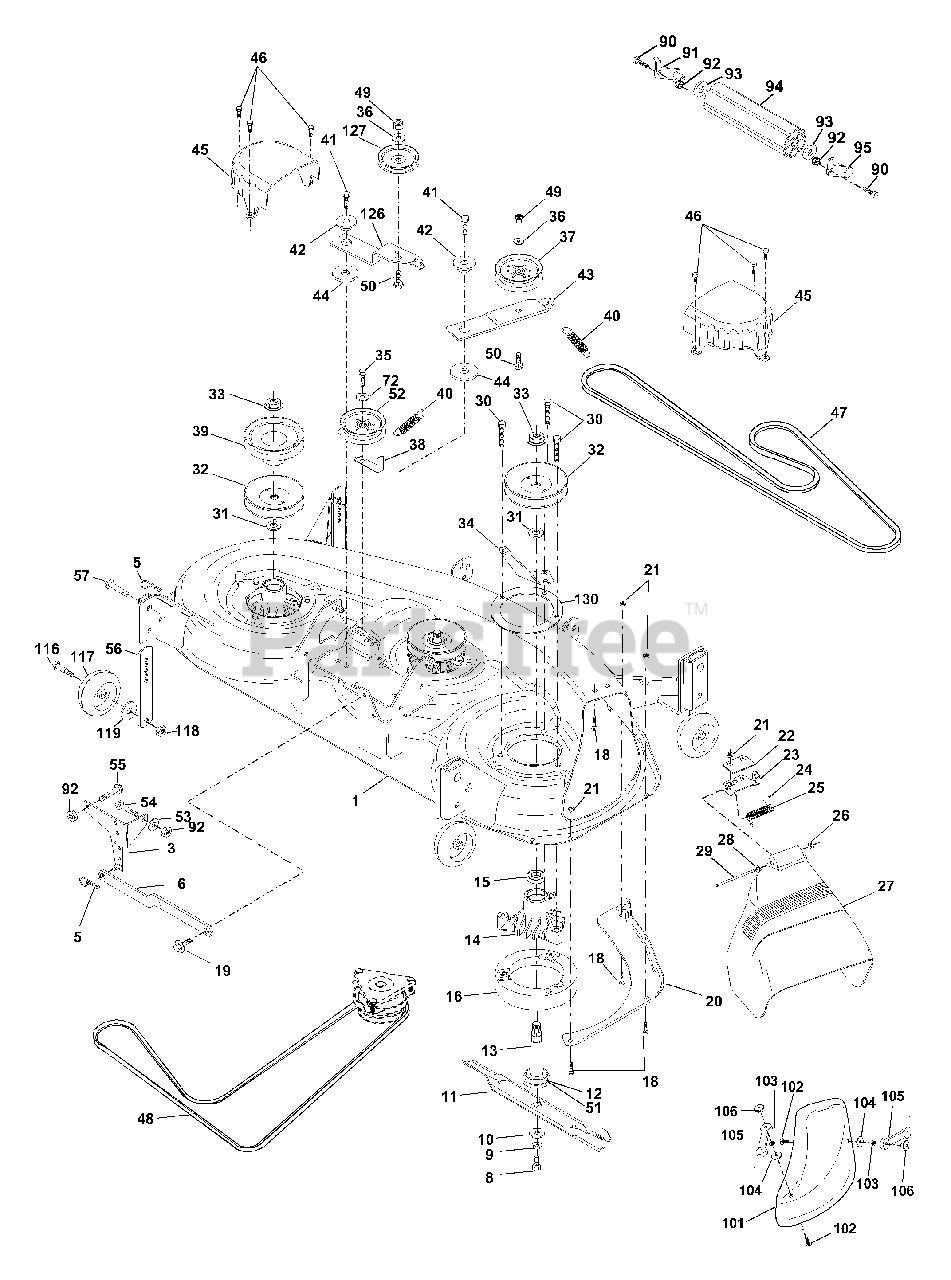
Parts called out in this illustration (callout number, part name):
1	Deck Asm., Mower 46"
3	Bracket Asm., Sway Bar
5	Retainer Spring
6	Arm, Suspension, Rear (Sway Bar)
8	Bolt, Patched 3/8-24 x 1-1/4 Gr. 8
9	Washer, Lock Hvy., Unplated 3/8
10	Washer, Hard Blade, Mower Vented
11	Blade, 46" Hi Perf
11	Blade, 46" Mulching
12	Bearing, Ball, Mandrel #6204
13	Shaft Asm. w/Lower Bearing
14	Housing, Mandrel
15	Bearing, Ball, Mandrel
16	Stripper, Mower Round
18	Bolt, Carriage 5/16-18 x 5/8
19	Bolt, Hex Head, Shoulder 5/16-18
20	Baffle, Vortex Mower 46"
21	Nut, Crownlock 5/16-18 UNC
22	Stiffener, Bracket
23	Bracket, Deflector
24	Cap, Sleeve
25	Spring, Torsion, Deflector
26	Nut, Push
27	Shield, Deflector Mower
28	Washer 11/32 x 5/8 x 16 Ga.
29	Rod, Hinge
30	Screw, Wsh Head, Thdroll
31	Washer, Spacer Mower Vented
32	Pulley, Mandrel
33	Nut, Flg. Top Lock Cntr. 9/16
34	Anchor, Spring Deck 46"
35	Screw, Thdroll 3/8-16 x 1-3/4 Tytt
36	Washer 13/32 x 13/16 x 16 Ga.
37	Pulley, Idler, Flat
38	Keeper, Belt, Idler
39	Pulley, Idler, Driven
40	Spring, Secondary 44/46/50 Vent
41	Screw 3/8-16 x 1-1/4
42	Spacer, Retainer
43	Arm, Idler Secondary
44	Washer,Hardened
45	Cover, Mandrel Deck
46	Screw, Thdroll. 1/4-20 x 5/8
47	V-Belt, Mower, Secondary
48	V-Belt, Mower, Primary
49	Nut, Crownlock 3/8-16 UNC
50	Bolt, Carriage 3/8-16 x 1-1/2 Gr. 5
51	Washer, Felt
52	Pulley Idler 46 Pri. Drive
56	Bar Adjusting Gage wheel
57	Pin Head Rivet
72	Washer 13/32 x 1 x 16 Ga.
90	Bolt, Fin, Hex 3/8-16 UNC x 1
91	Bracket, Asm Noseroller, LH
92	Nut, Lock, Hex w/Ins 3/8-16UNC
93	Washer 17/32 x 7/8 x 16 Ga.
94	Roller, Nose 38 & 42
95	Bracket, asm Noseroller RH
101	Cover Mulcher 46" Black
102	Screw Phillips Truss Head
103	Washer Lock #10
104	Washer #10
105	Latch Asm mulch/Bagger
106	Nut Weld
116	Bolt, Shoulder
117	Gauge Wheel
118	Nut, Centerlock 3/8-16 UNC
119	Washer 3/8 x 7/8 x 14 Ga.
126	Arm, Idler, Primary Deck 46"
127	Pulley, Idler, V-Groove Dim. 4.25
